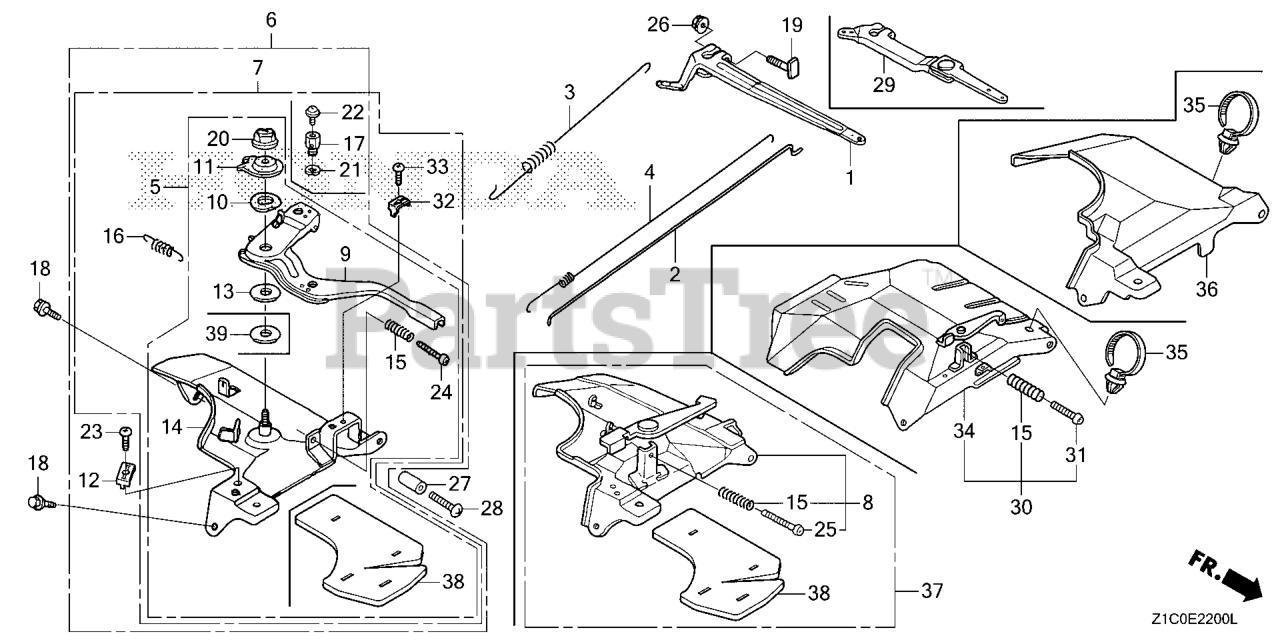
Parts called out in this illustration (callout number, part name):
1	ARM, GOVERNOR
2	ROD, GOVERNOR
3	SPRING, GOVERNOR
4	SPRING, THROTTLE RETURN
7	CONTROL ASSY.
9	LEVER, CONTROL
10	SPRING, LEVER
11	WASHER, CONTROL LEVER
13	SPACER, CONTROL LEVER
14	BASE, CONTROL
15	SPRING, CONTROL ADJUSTING Use from Engine SN 2327377.
16	SPRING, CABLE RETURN
17	HOLDER, WIRE
18	BOLT, FLANGE (6X12) (CT200)
19	BOLT, GOVERNOR ARM
20	NUT, SELF-LOCK (6MM)
21	CIRCLIP (5MM) Use from Engine SN 2327377.
22	SCREW, PAN (4X6)
24	SCREW, PAN (5X32)
26	NUT, FLANGE (6MM)
32	HOLDER, CABLE
33	SCREW, PAN (5X16)
